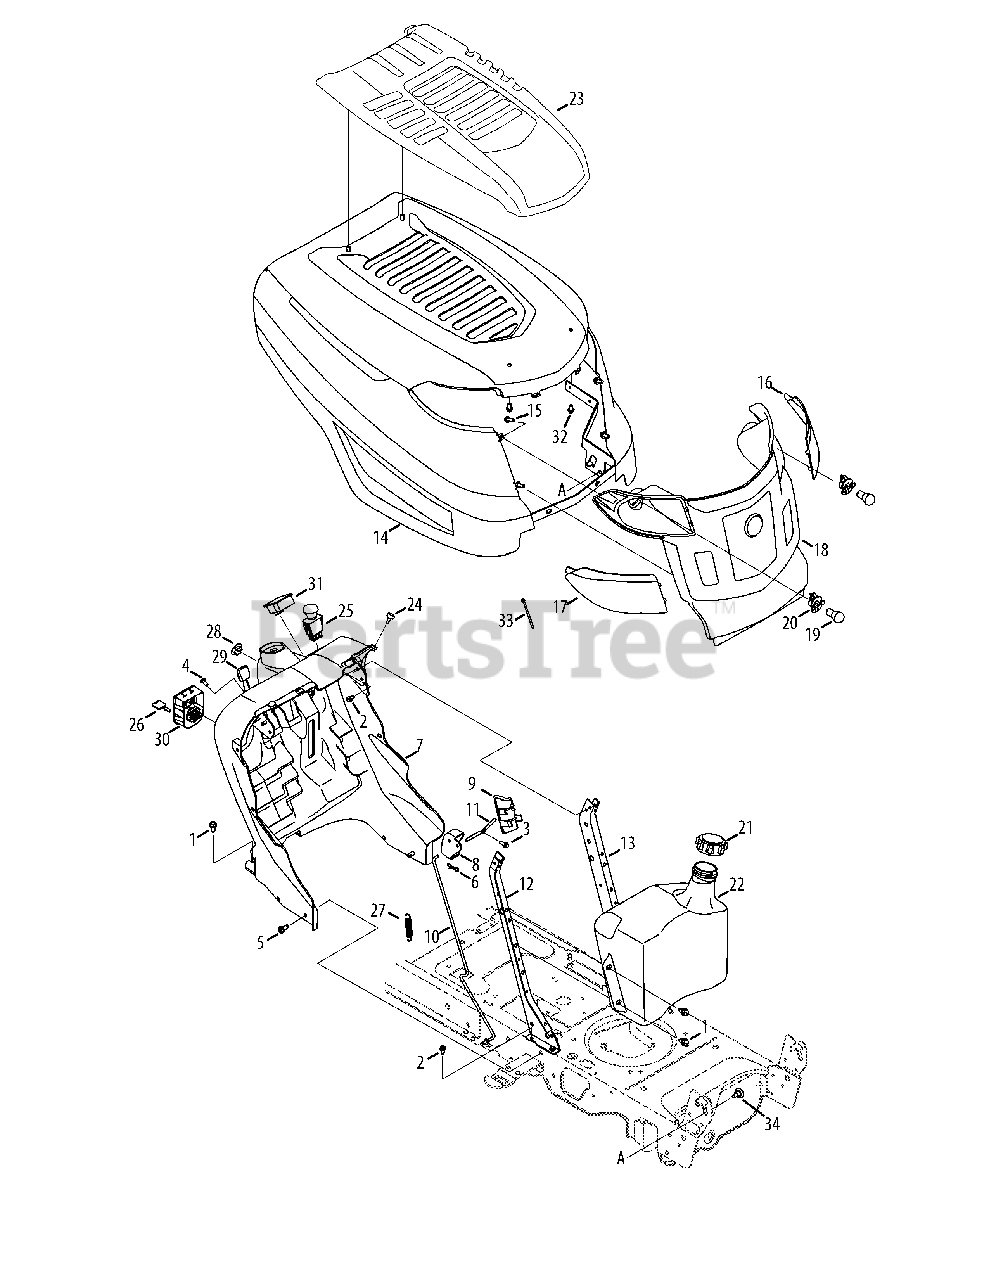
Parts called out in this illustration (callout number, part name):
1	Taptite Screw,5/16-18:.750
2	Taptite Screw,1/4-20:0.500
3	Hi-Lo Screw, 1/4-15:0.750
4	Screw, 1/4-14:0.625
5	Taptite Screw, 5/16-18:0.750
6	Bow Tie Cotter Pin
7	Dash Panel
8	Dash Lever
9	Cruise Cover
10	Control Rod
12	RH Support Plate
13	LH Support Plate
14	Hood Assembly
15	Screw, 1/4 DIA:.750
20	Lamp Socket
21	Fuel Cap
25	Electric PTO Switch
27	Extension Spring, .500 DIA x 2.733 LG
28	Choke Plug
29	Throttle/Choke Cable
30	Key Switch Module
31	Hour Meter
32	Screw, 1/4-15 x .50
33	Cable Tie, 3/16 X .05 X 7.4
34	Shoulder Screw, .43 X .29:5/16-18
